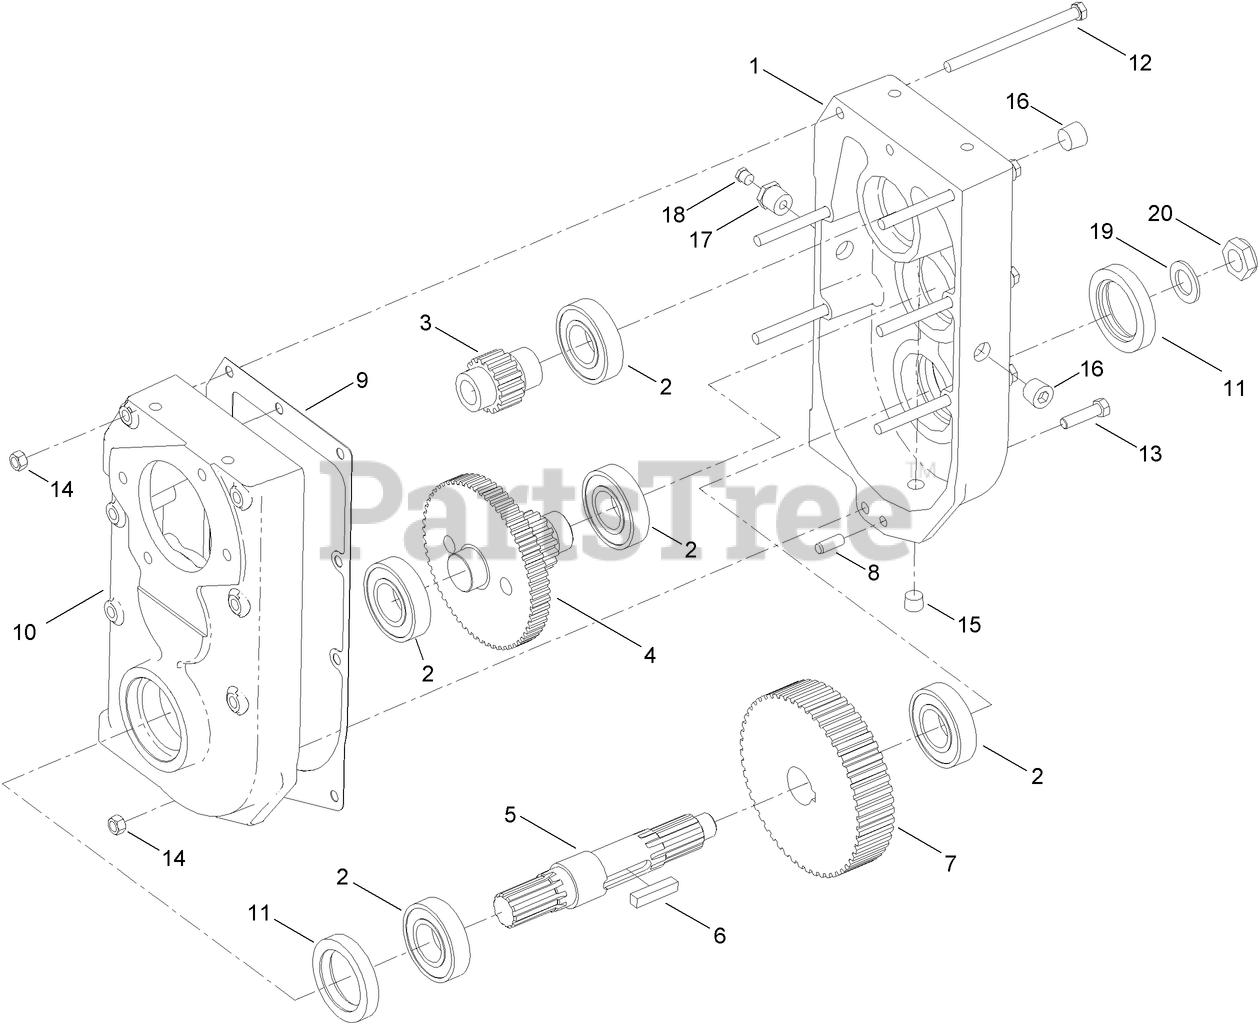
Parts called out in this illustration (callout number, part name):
1	CASE-GEAR
2	BEARING
3	GEAR-MOTOR, 18 TEETH
4	GEAR-CLUSTER, 59/15 TEETH
5	SHAFT-OUTPUT
6	KEY-SQUARE
7	GEAR-REDUCTION, 51 TEETH
8	PIN-DOWEL
10	CASE-GEAR
11	SEAL-OIL
12	SCREW-HH
13	SCREW-HH
15	FITTING-HYD
16	PLUG-PIPE, HEX SOCKET
17	FITTING-STRAIGHT
20	NUT-LOCK, NI
